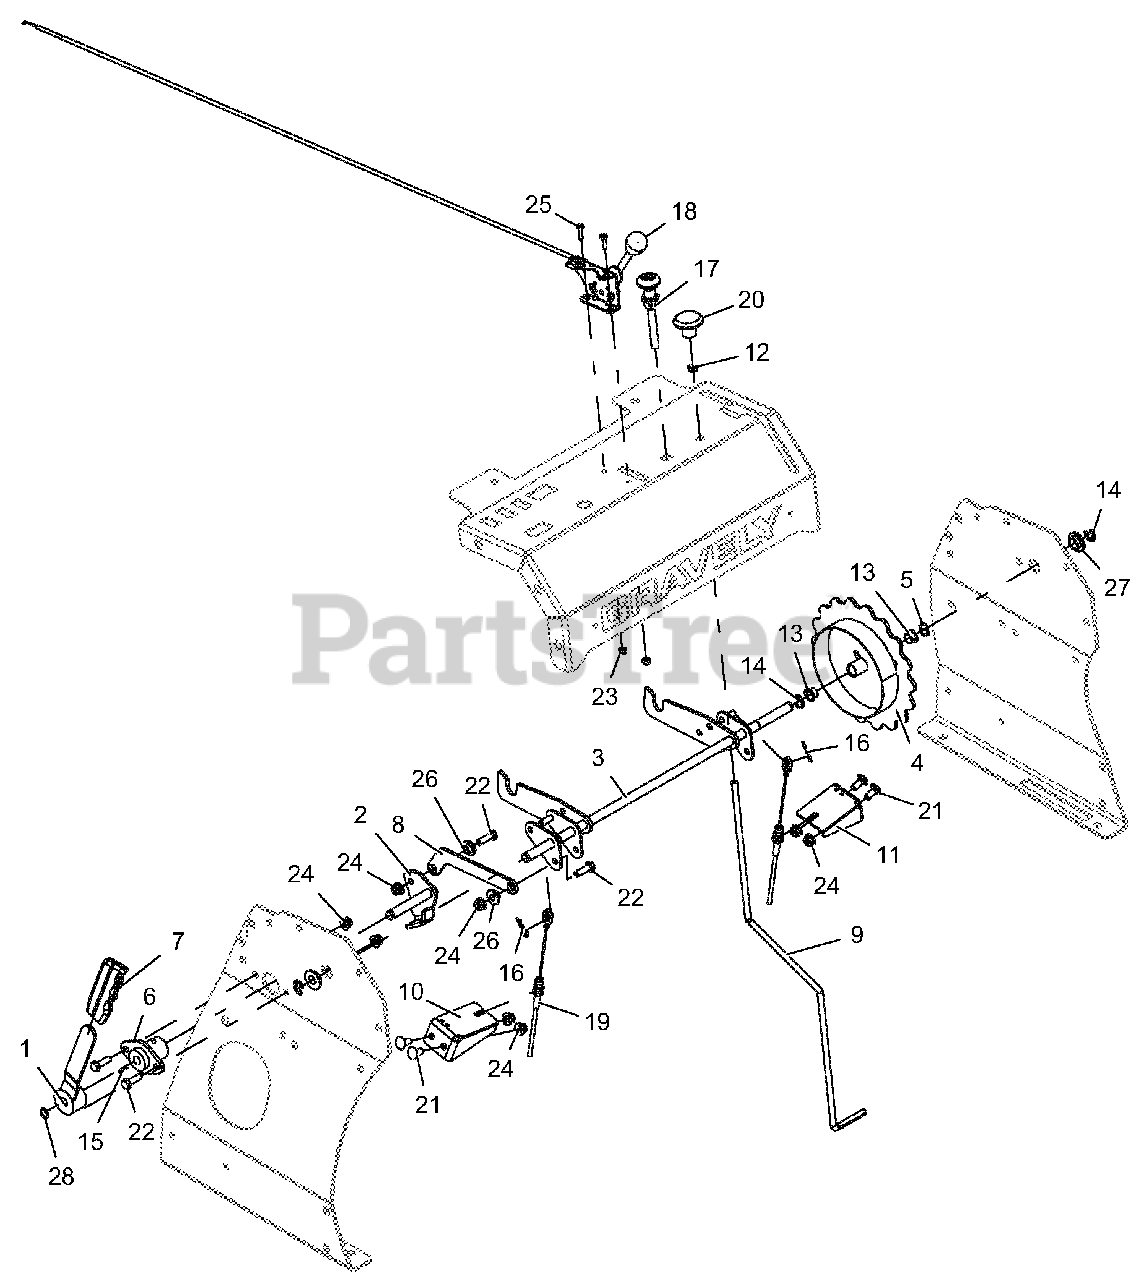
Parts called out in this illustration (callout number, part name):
1	WLDMT, PARKING BRAKE LEVER
2	WLDMT, PARKING BRAKE ACTUATING
3	WLDMT, BRAKE INTERLOCK
4	WLDMT, HEIGHT OF CUT
5	WAVE WASHER .531 x .781 x .125 FH
6	BSHG, FLANGE .500 ID
7	GRIP, PARKING BRAKE (YELLOW)
8	LINK, INTERLOCK
9	WIREFORM, TRAILER LOCK
10	BRKT, CABLE MTG.
11	BRKT, LH CABLE MTG
12	BSHG, POLYLINER - .38 SNAPIN
13	BUSHING, POLYLINER - .50 SPLIT
14	RG-RTNG-EXT .500 x .042 (E)
15	KEY, WDRF .13 x .63 HRD#5 GM124545 P
16	PIN, HAIR INT .08 x .18 x 1.18 YWZC
17	CABLE, CHOKE (SNAP IN)
18	CABLE, PRO-CONTROL THROTTLE
19	CABLE, PROSTANCE P. BRAKE
20	KNOB, PUSH -PULL .312-18
21	BLT-RDHDSQNK .31-18 x .75 G5 YWZC
22	BLT-HEX .31-18 x 1.00 GR5 YWZC
23	NUT-LK-NYL #10-24 YWZC
24	NUT-LK-NYL-FLG .31-18 YWZC
25	@SCR-MCH 10-24 x .75 HWH YWZC
26	BSHG, FLG .32 x .500 .344 x .880
27	BSHG, FLANGE .515 x .750 x .31 x 1.12
28	RG-RTNG-EXT .500 x .050
